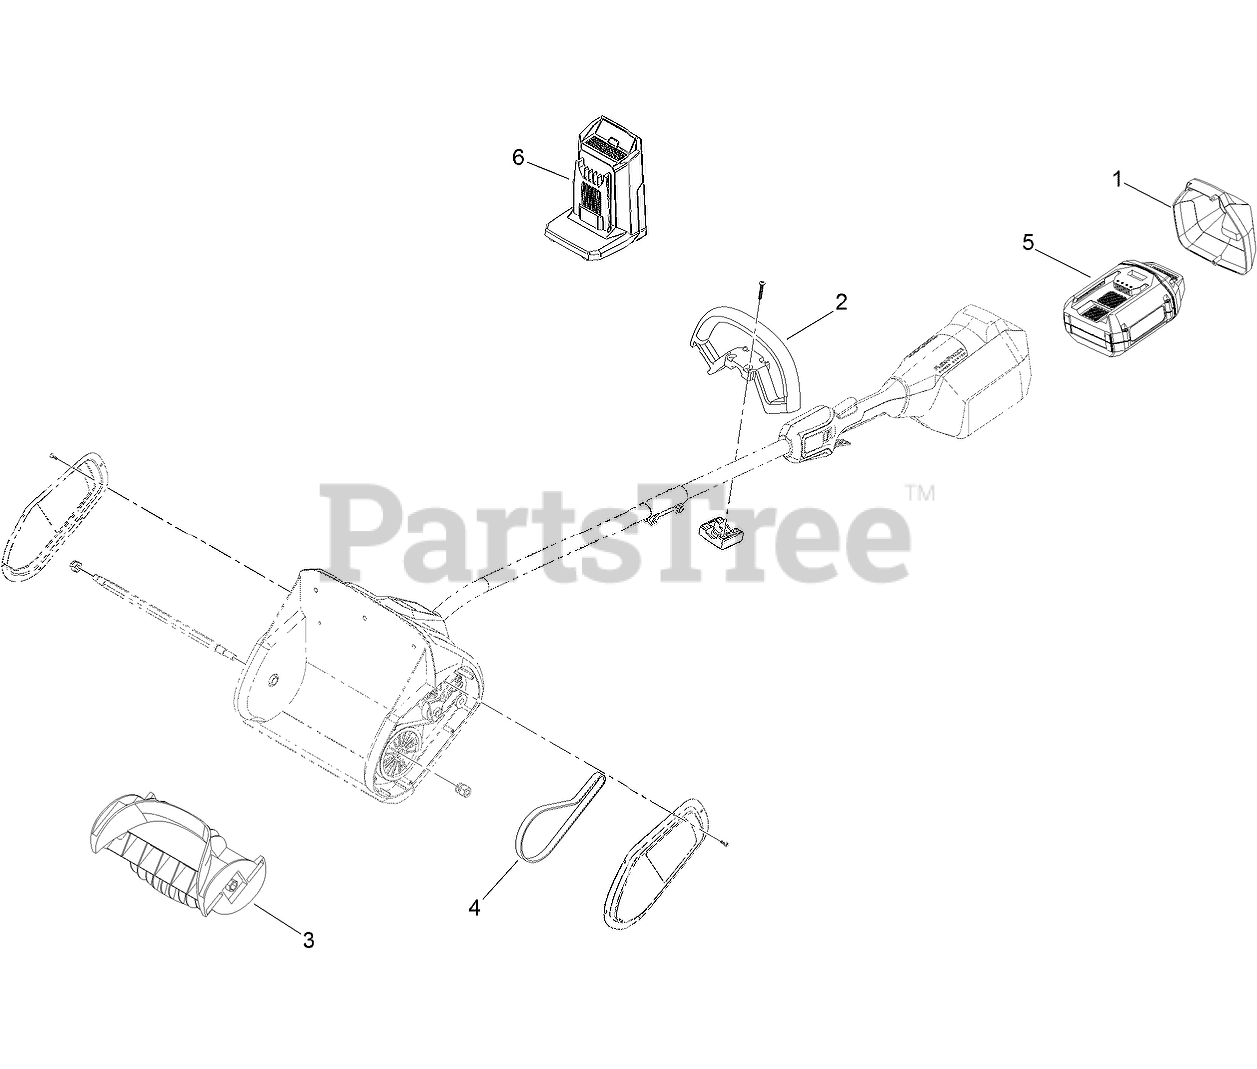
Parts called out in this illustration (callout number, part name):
1	COVER-BATTERY
2	HANDLE-TRIMMER
4	BELT-DRIVE
5	BATTERY-60V, 1P 2.5AH
6	CHARGER-60V
